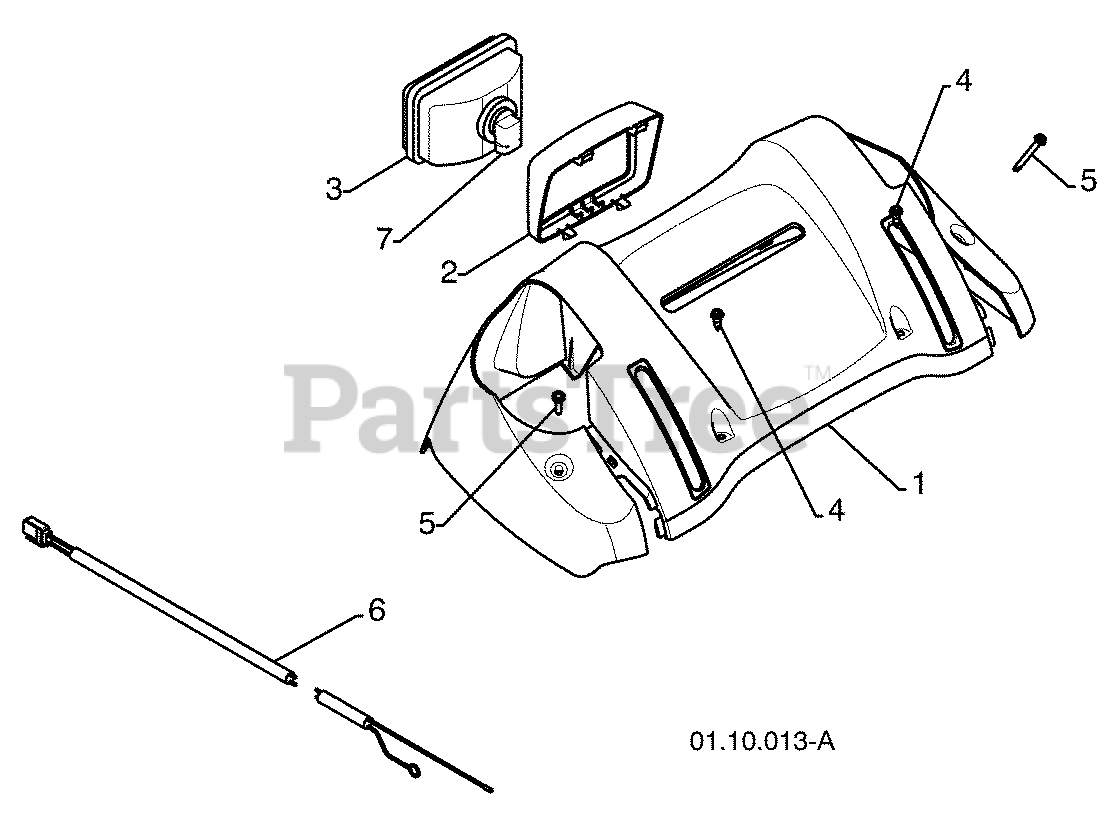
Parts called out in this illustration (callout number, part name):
1	PANEL CONSOLE GRAY
2	HEADLIGHT BEZEL GRAY
3	HALOGEN HEADLIGHT
4	SHOULDER SCREW
5	SCREW 10-24 X 1.25
6	WIRE HARNESS
